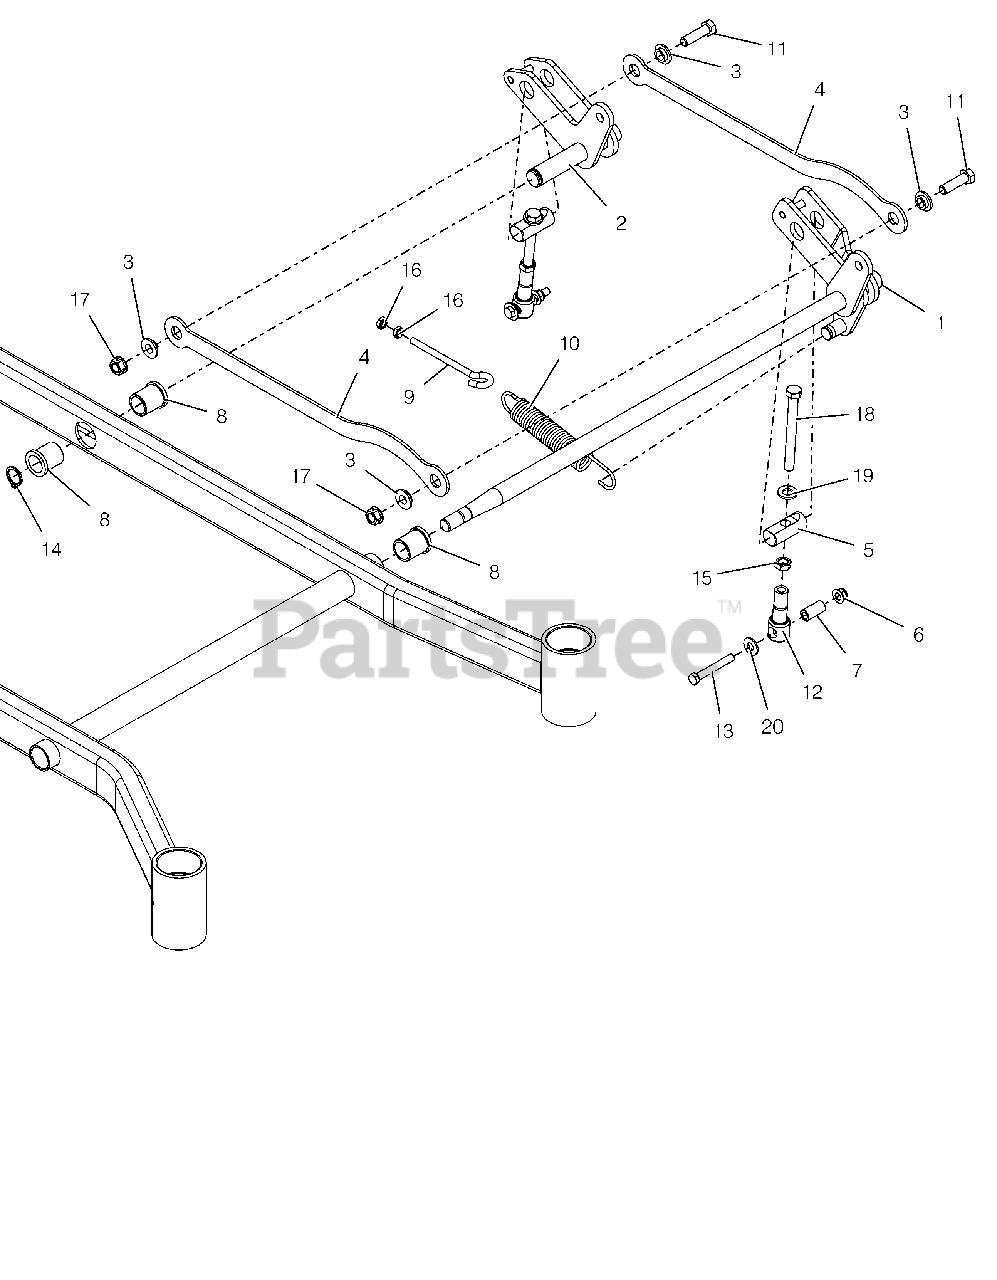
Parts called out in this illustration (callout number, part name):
1	FRT LH DECK LIFT ARM WMT- LF
2	REAR LH DECK LIFT ARM WMT- LF
3	BSHG-FLG .515X.750X.310X1.120
4	LINK, LIFT
5	PIN, DECK LIFT
6	@NUT-LK-NYL-FLG .38-16 YWZC
7	SPACER, DECK LEVELING
8	BSHG-FLG 1.00X1.25X1.50X1.50
9	BOLT,.38-16 X 4.25-.62 DIA EYE
10	SG-TENS .162X1.25X8.25 WLD 25
11	@BLT-HEX .50-13X1.75 GR5 YWZC
12	LINK, DECK LIFT FORMED
13	BLT-HEX .38-16X2.75 GR8 YWZC
14	RG-RTNG-EXT 1.00X.078
15	NUT-JAM .50-13 YWZC
16	NUT-HEX-JAM .375-16 YWZC
17	NUT-LK-CTR-FLG .50-13 YWZC
18	BOLT, 1/2-13 X 5.0 2.5 THREAD
19	FLATWASHER 1/2 SAE HARD 15906
20	@WSHR-FL-STL.438X1.00X.083 YWZ
